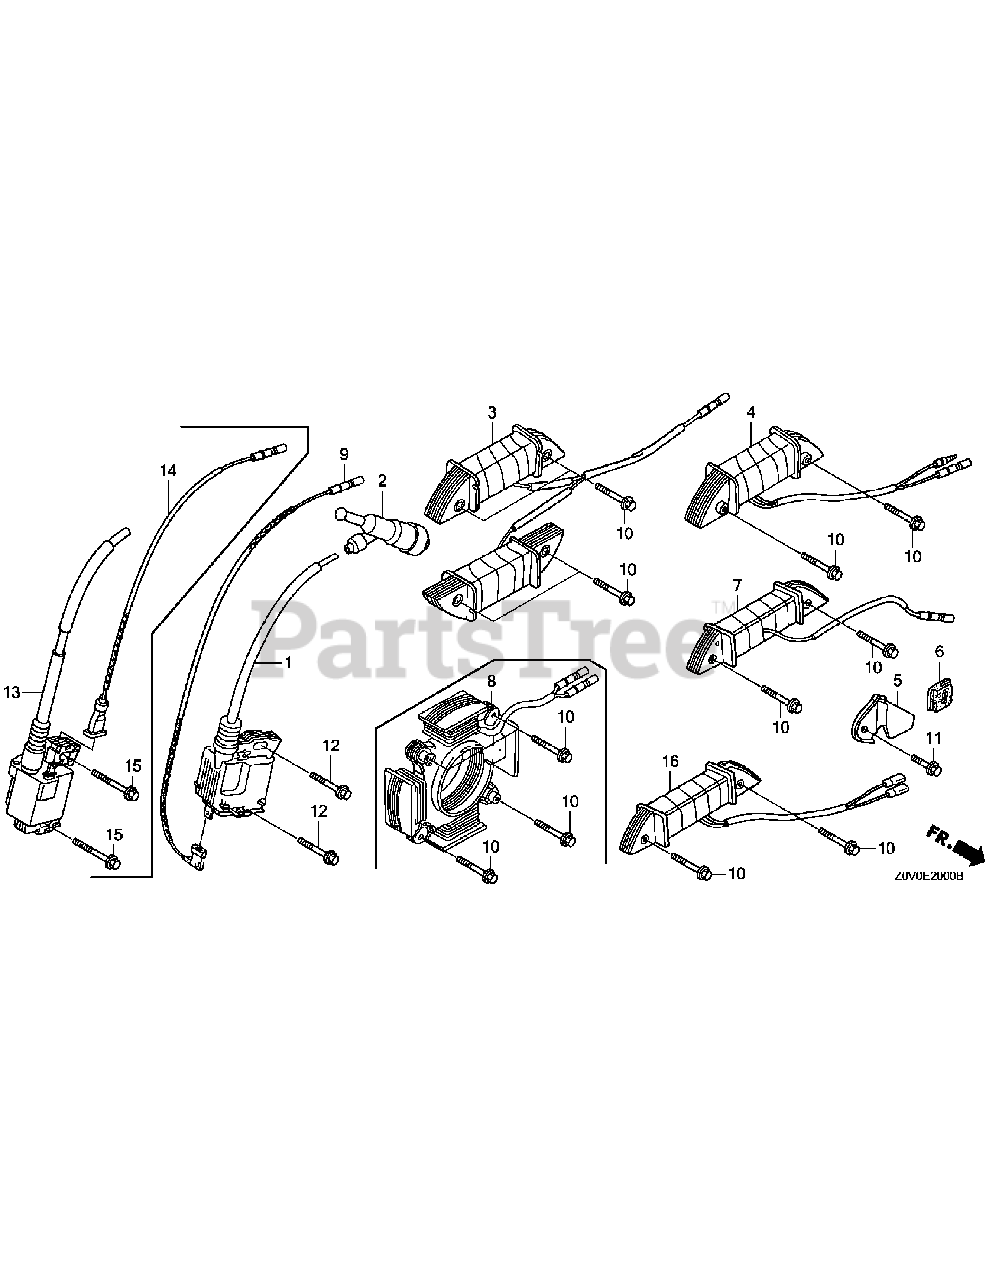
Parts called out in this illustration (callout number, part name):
1	Coil Assy., Ignition
2	Cap Assy., Noise Suppressor
3	Coil Assy., Lamp(12V/50W)
4	Coil Assy., Lamp(12V/25W)
5	Clamper, Cord
6	Grommet, Cord
7	Coil Assy., Charge(1A)
8	Coil Assy., Charge(12V-7A)
9	Cord, Stop Switch(370Mm)
10	Bolt, Flange, 6X28(Ct200)
11	Bolt, Flange, 5X10
12	Bolt, Flange, 6X25(Ct200)
13	Coil Assy., Ignition
14	Cord, Stop Switch(490Mm)
15	Bolt, Flange, 6X28(Ct200)
16	Coil Assy., Charge
